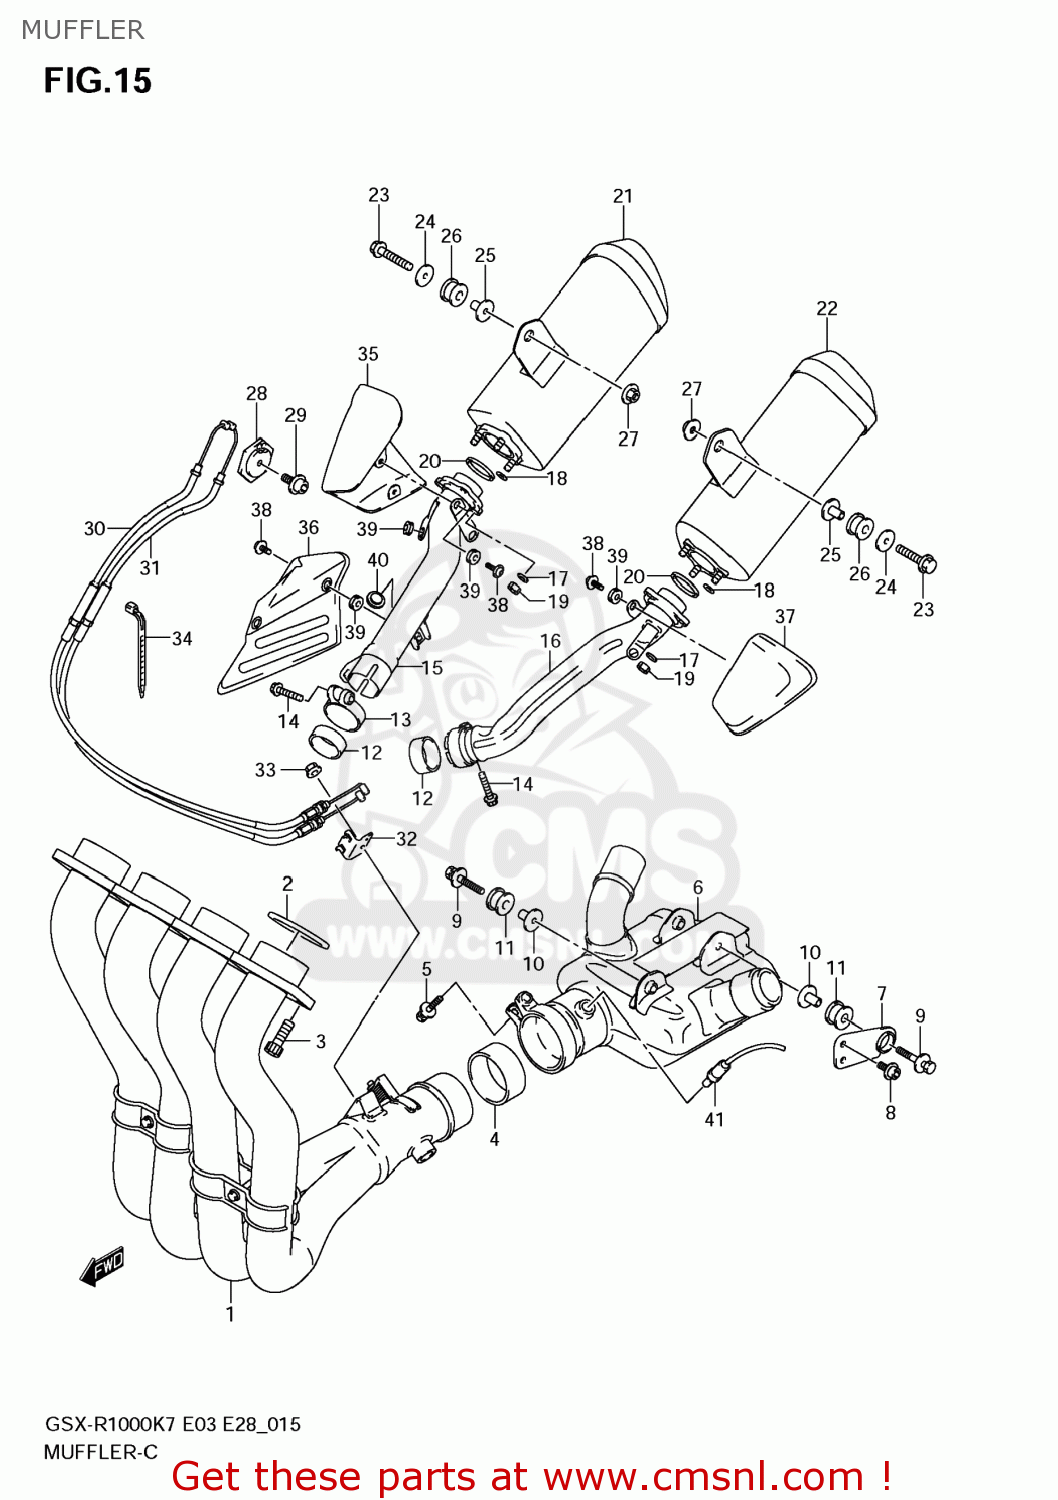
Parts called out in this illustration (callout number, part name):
1	PIPE,EXHAUST
2	GASKET,EXHAUST PIPE (NAS)
3	BOLT
4	CONNECTOR,CHAMBER
5	BOLT(8X40)
6	CHAMBER
7	BRACKET,CHAMBER SPRT
8	BOLT
9	BOLT 8X45
10	SPACER(8.6X12X24.2)
11	CUSHION
12	CONNECTOR,EXHAUST,R
13	CLAMP,CONNECTOR
14	BOLT(8X40)
15	PIPE,JOINT,R
16	PIPE,JOINT,L
17	WASHER(8.5X18X1.6)
18	O RING(D:1.9,ID:7.8)
19	NUT
20	GASKET,EXHAUST PIPE (NAS)
21	BODY,MUFFLER,R
22	BODY,MUFFLER,L
23	BOLT(8X45)
24	WASHER(8.5X28X1.5)
25	SPACER(8.6X12X24.2)
26	CUSHION
27	NUT
28	PULLEY CONTROL
29	BOLT
30	CABLE,EXHAUST VALVE NO.1
31	CABLE,EXHAUST VALVE NO.2
32	BRACKET,EXHAUST VALVE CABLE
33	NUT
34	CLAMP(L:125)
35	COVER,JT,R
36	COVER,JT,R NO.2
37	COVER,JT,L
38	SCREW(6X12)
39	CUSHION
40	CUSHION
41	SENSOR,OXYGEN
